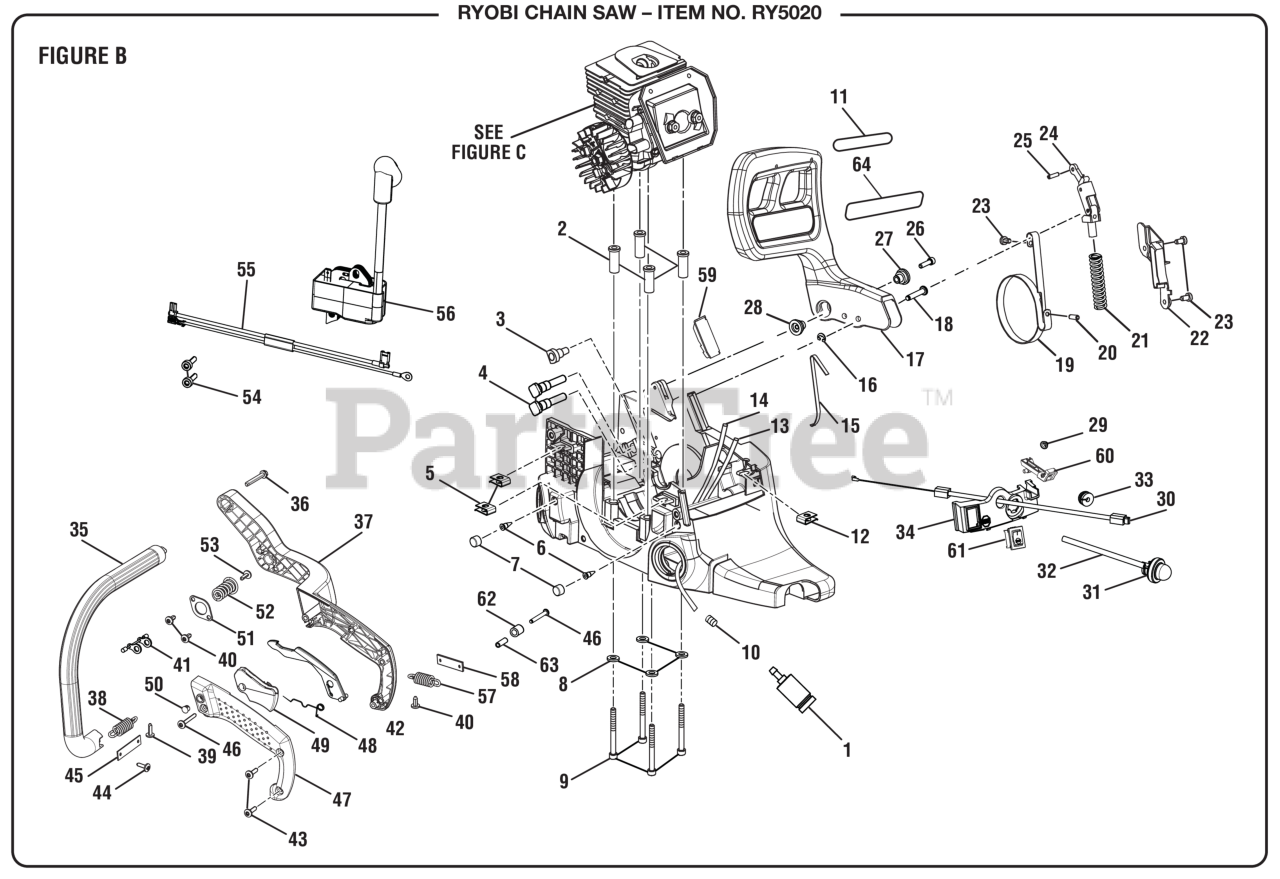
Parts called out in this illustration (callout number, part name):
1	Fuel Filter
2	Spacer Insert
3	GROMMET, OIL OUTLET
4	Control Panel, Black
5	Speed Nut ("U"-type)
6	Front Handle, Black
7	Front Handle, Gray
8	Washer (ID5.8 x OD11.5 x 1.7t)
9	Screw (10-24 X 2 in. Soc. Cap Hd.)
10	Filter Spring Clamp
11	Pull To Release Brake Label
12	Screw (10-14 x 1/2 in.)
13	Inlet Tubing (166 mm)
14	Cupped Washer
15	Screw (10-14 x 3/4 in.)
16	Screw (10-14 Thread Twin Helix)
17	Hand Guard Assembly
18	HAND GUARD ACTUATING PIN
19	Chain Brake Band Kit
20	Roll Pin (Big)
21	SPRING, COMPRESSION
22	Chain Brake Cover
23	Screw (#8-16 x 5/16 in., T25 Torx Pan Hd. T.F.)
24	Chain Brake Link Assembly
25	Spring Pin (Small)
26	Screw (8-32 X 5/8 in. Hex Soc. Hd.)
27	Screw (10-24 x 5/8 in.)
28	Screw (8-32 x 5/8 in.)
29	Ignition Switch Harness
30	THROTTLE CABLE
31	Primer Bulb
32	Primer Tubing (64 mm)
33	Grommet, Wire Harness (Split)
34	Control Panel
35	Front Handle, Black
36	SCREW (12-14 x 1-1/2 in.)
37	Rear Handle, Black
39	Screw, Truss Hd., Plastite (10-14 x 5/8")
40	Screw (10-14 x 1/2 in., Torx Truss Hd. T.F.)
41	Limiter (Upper Isolator Spring)
42	Trigger Release
43	Screws (10-14 x 3/4 in., T25 Torx Pan Hd. T.F.)
44	Screw (10-14 Thread Twin Helix)
45	Spring Retainer
46	SCREW (10-14 x 1-3/8 in.)
47	Handle Cover, Black
48	Torsion Spring
50	PLUG-PLASTIC
51	Isolator Plate
52	Isolator Spring
53	Screw (10-24 X 5/8 in. Torx Hd.)
54	Screw, Thread Form (8-32 x 5/8")
55	Ignition Switch Assembly
56	Ignition Module Assembly
58	Spring Retainer
60	Choke Lever
61	Stop Switch (Momentary Contact)
62	Rubber Bumper
63	Spacer (Spring Screw)
64	Chain Brake Label
